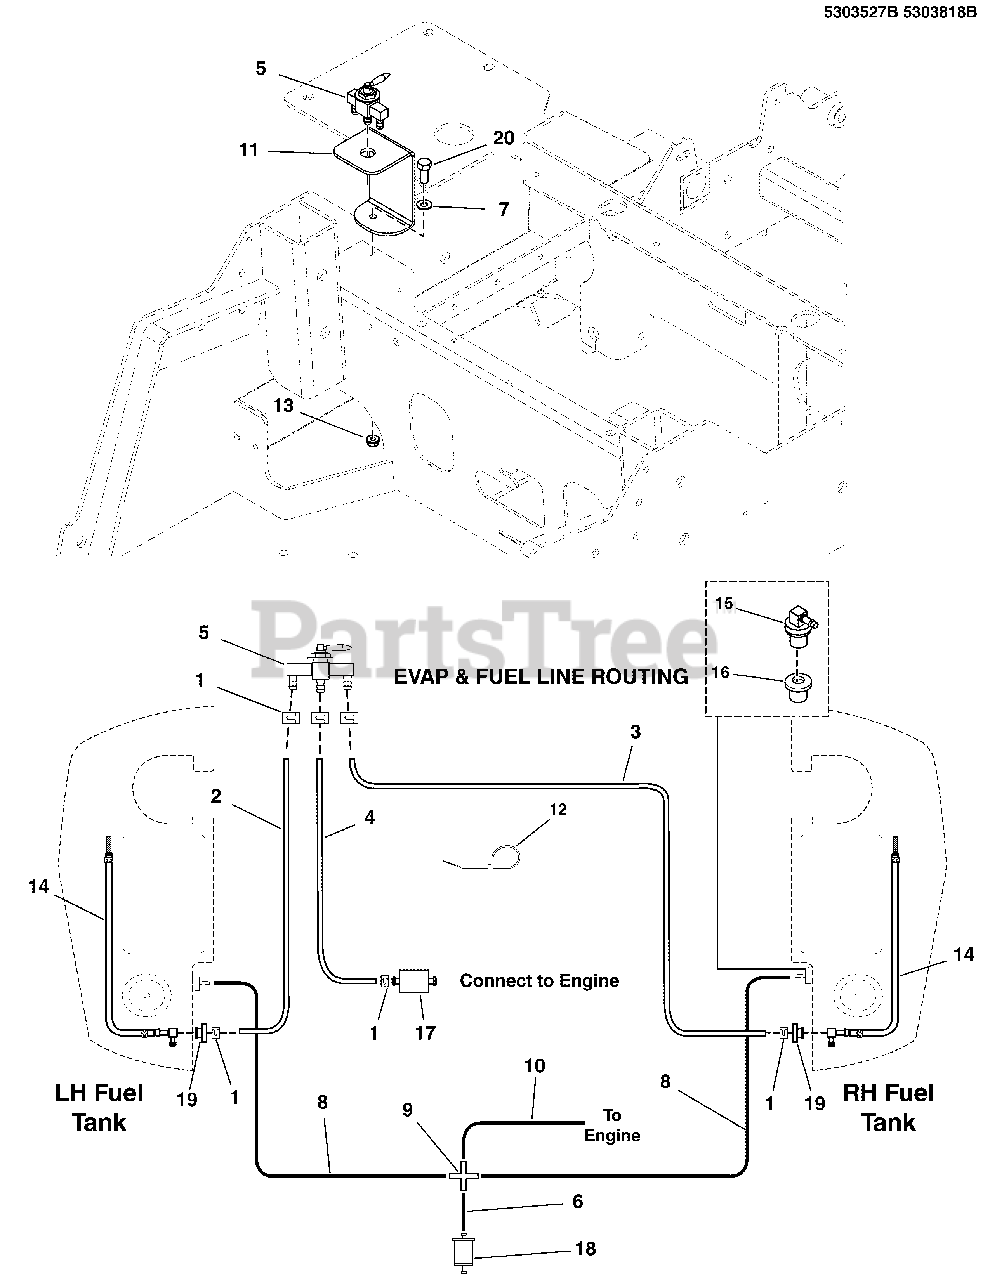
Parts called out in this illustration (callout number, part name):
1	CLAMP, HOSE, EXTERNAL, 1/2 - RED
2	HOSE, 1/4" FUEL, 11.00"
3	HOSE, 1/4" FUEL, 27.00"
4	HOSE, 1/4" FUEL, 19.50"
5	VALVE, FUEL SHUT-OFF, 11772
6	HOSE, VAPOR, 5MM ID, 4.00 LG
7	WASHER, 5/16 SAE
8	HOSE, VAPOR, 5MM ID, 23.00 LG
9	FITTING, BARBED CROSS, 3/16" BLK NYLON
10	HOSE, VAPOR, 5MM ID, 22.00 LG
11	MOUNT, FUEL VALVE, 2100Z - BLK
12	TIE,SELF-LOCKING, 6"
13	NUT, 5/16-18 HEX NYLOCK FLANGE
14	HOSE ASSEMBLY (SV)
15	REMOTE, VENT ASSEMBLY, NO VALVE (SV)
16	GROMMET (SV)
17	FUEL FILTER (SV)
18	FILTER, FUEL
19	BUSHING-FUEL TANK RED RUBBER (SV)
20	BOLT, 5/16-18 X 3/4 GD5
